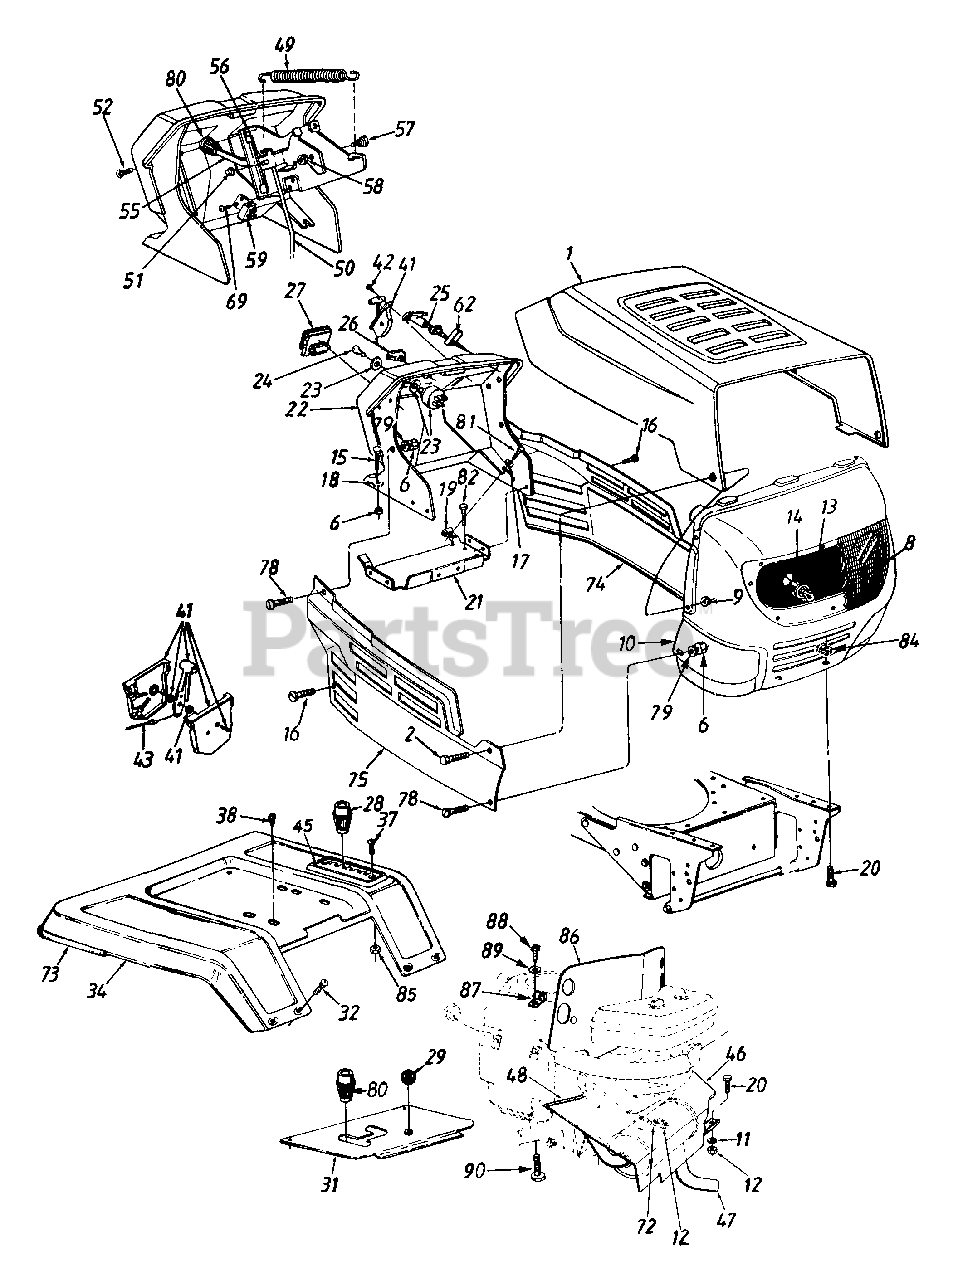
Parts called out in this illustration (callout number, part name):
6	Hex Nut 1/4-20 Thd.
8	Headlight Lens
9	Flange L-Nut 1/4-20 Thd.
11	L-Wash. 5/16" I.D.
12	Hex Nut 5/16-18 Thd.
13	Lamp
14	Socket
15	Carriage Bolt 1/4-20 x 1.0" Lg.
16	Hex Wash. Hd. TT-Tap Scr. 1/4-20 x .5" Lg.
17	Fl-Wash..281" I.D. x .73" O.D.
18	Bolt Retainer 1/4" I.D.
19	Speed Nut 1/4-20 Thd.
20	Hex Bolt 5/16-18 x .75" Lg.
23	Ignition Switch
24	Ignition Key
25	Choke Control
26	Light Switch
27	Ammeter
28	Shift Knob
32	Carriage Bolt 1/4-20 x .5" Lg.
38	Hex Wash. Hd. AB-Tap Scr. 5/16 x .75" Lg.
41	Throttle Box Ass'y.
42	Truss Mach. AB-Tap Scr. #10 x .5" Lg.
43	Throttle Control Wire 35" Lg.
45	6-Speed Selector Plate
46	Front Heat Shield
47	Muffler
48	Trim Strip 12" Lg.
49	Ext. Spring 5.06" Lg.
50	Deck Control Rod
51	Speed Nut 1/4" Rod
52	Torx Mach. Scr. 1/4 x 62" Lg.
55	PTO Lever
56	PTO Bracket
57	Shld. Bolt .437" Dia. x .162"
58	Hex L-Nut 5/16-18 Thd.
59	Safety Switch (PTO)
62	Retainer Clip
69	Hex Wash. Hd. B-Tap Scr. #10 x .38" Lg.
72	Spec. L-Wash. 5/16" I.D.
73	Trim Strip 81" Lg.
79	Bell-Wash. 1/4" I.D.
80	Small Shift Knob
81	Hex TT-Tap Scr. 1/4-20 x .75" Lg.
82	Hex AB-Tap Scr. 1/4 x .62" Lg.
84	U-Nut 5/16-18 Thd.
85	Hex Sems Nut 1/4-20 Thd.
86	Top Heat Shield
87	Clamp
88	Truss Mach. Scr. #10 x .5" Lg.
89	Fl-Wash. 188" I.D. x .43" O.D.
90	Hex L-Wash. TT-Tap Scr. 3/8-16 Thd.
